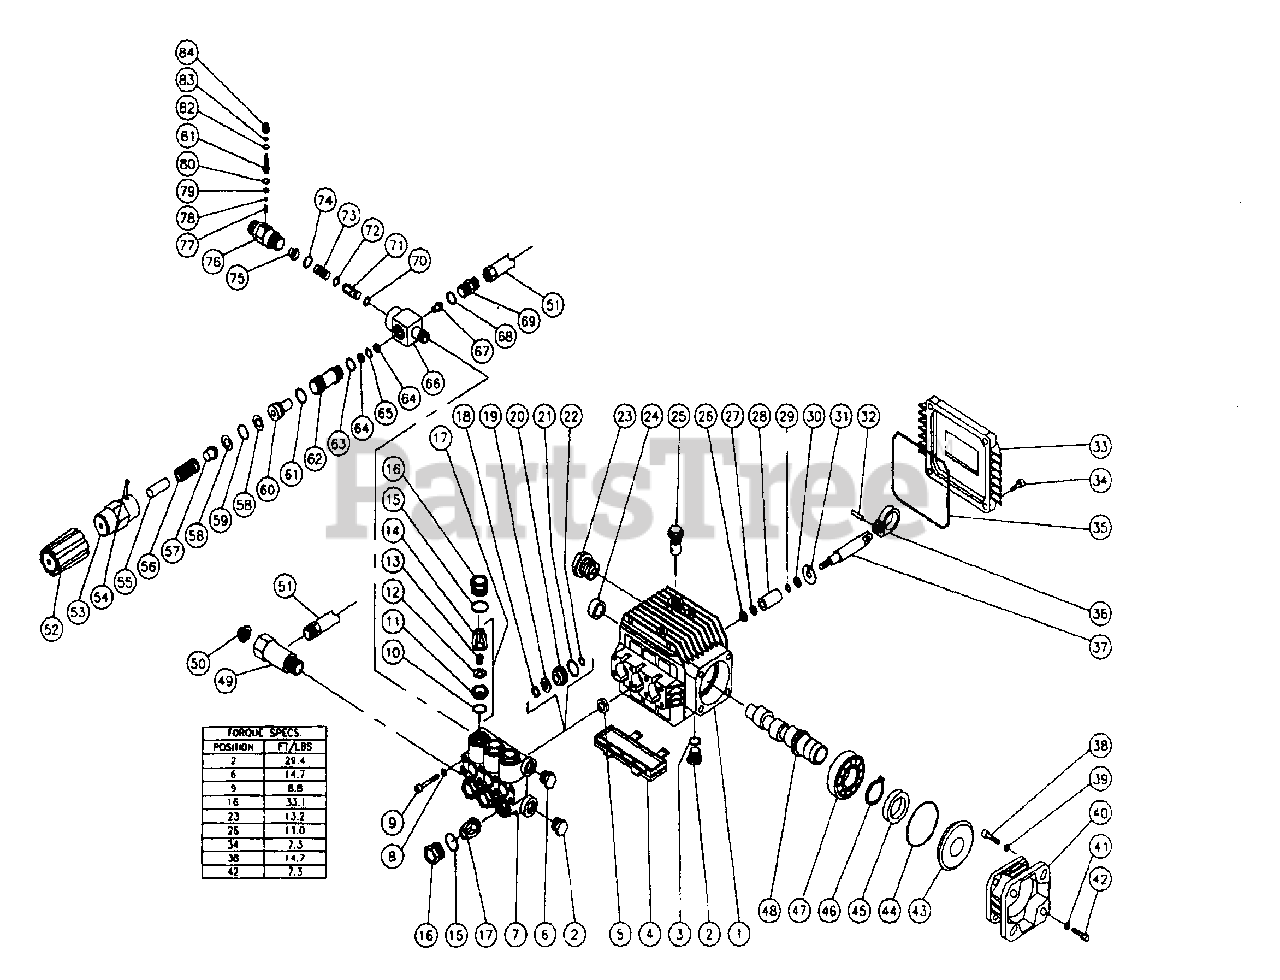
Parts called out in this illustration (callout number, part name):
1	Crankcase
2	Hex Plug
4	Drip Pan
5	Oil Seal
6	Hex Plug
7	Manifold-Brass
8	Lockwasher
9	Bolt
10	O-ring
11	Valve Seat
12	Valve Plate
13	Valve Spring
14	Valve Cage
16	Valve Plug
17	Valve Assembly
18	Head Ring
19	V-Packing
20	V-Packing Retainer
23	Oil Level Indicator
24	Needle Bearing
25	Oil Dip Stick
26	Nut
30	Back-up Ring
32	Connecting Rod Pin
33	Crankcase Cover
34	Bolt
36	Connecting Rod
37	Piston Guide
38	Bolt
39	Lockwasher
41	Lockwasher
42	Bolt
45	Oil Seal
46	Snap Ring
47	Ball Bearing
48	Crankshaft
49	Inlet Fitting
50	Inlet Screen
51	By-Pass Hole
52	Plastic Adjustable Knob
53	Adjusting Knob
54	Stop Adjusting Knob
55	Spring Guide
57	Spring Seat
58	Back-up Ring
59	O-ring
61	O-ring
62	Barrel Stem Retainer
64	Back-up Ring
65	O-ring
66	Unloader Body
67	Ball Piston
68	O-ring
69	By-pass Seat
70	O-ring
71	Backflow Check
72	O-ring
73	Check Spring
75	Injector Orifice
76	Injector
77	Ball
78	Spring
79	O-ring
80	O-ring
81	Hose Barb
84	Adjustment Knob
